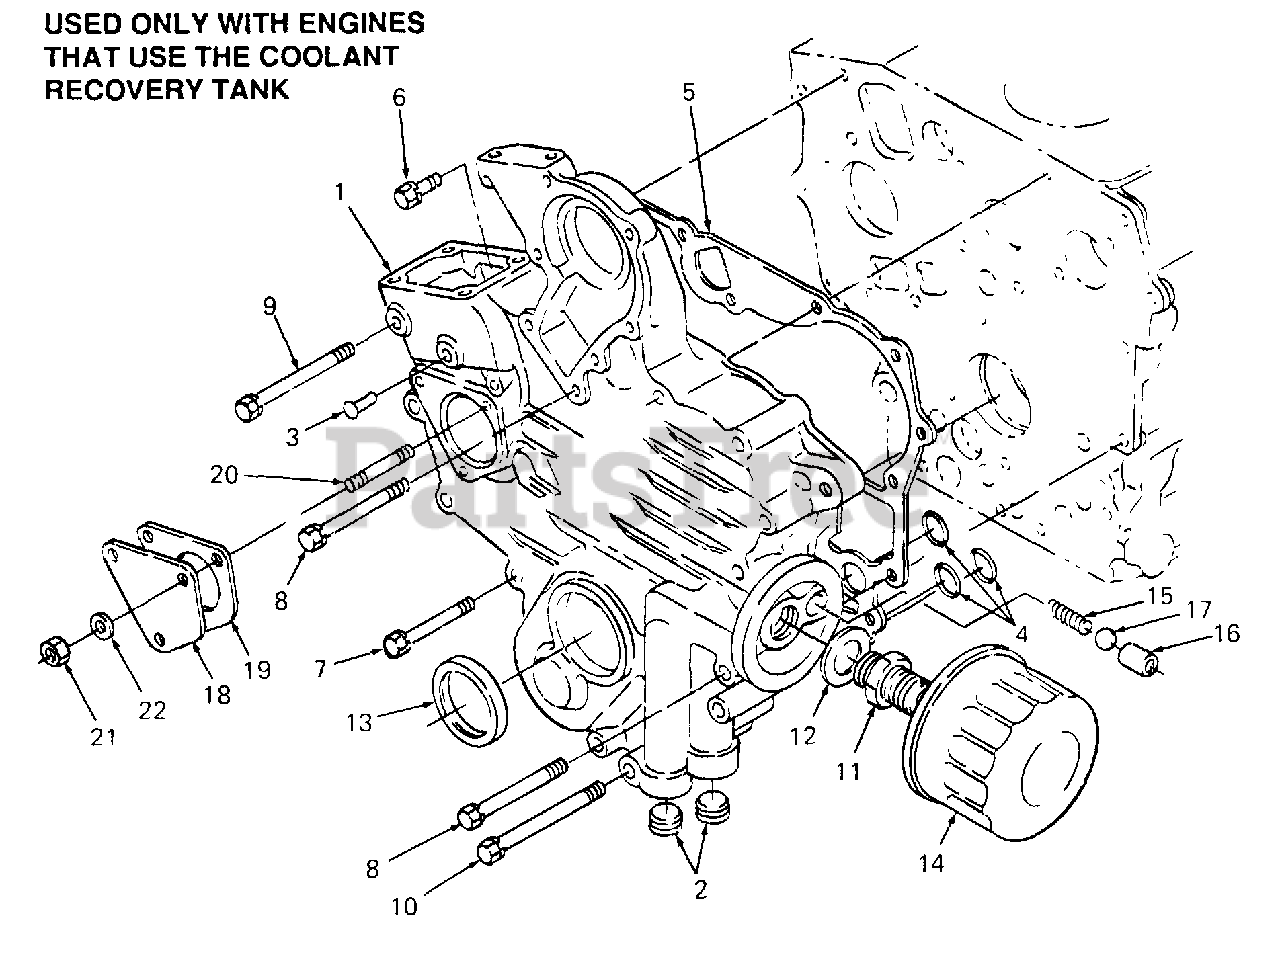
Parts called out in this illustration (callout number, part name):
1	Case Assy, Gear [Includes Ref No. 2 (Qty 2) & 3]
4	O-Ring, 1/2 X 11/16
5	Gasket, Gear Case
6	Screw, Hex Cap w/Washer
7	Screw, Hex Cap
8	Screw, Hex Cap w/Washer
9	Screw, Hex Cap
10	Screw, Hex Cap
14	Element, Filter
22	Washer, Spring
